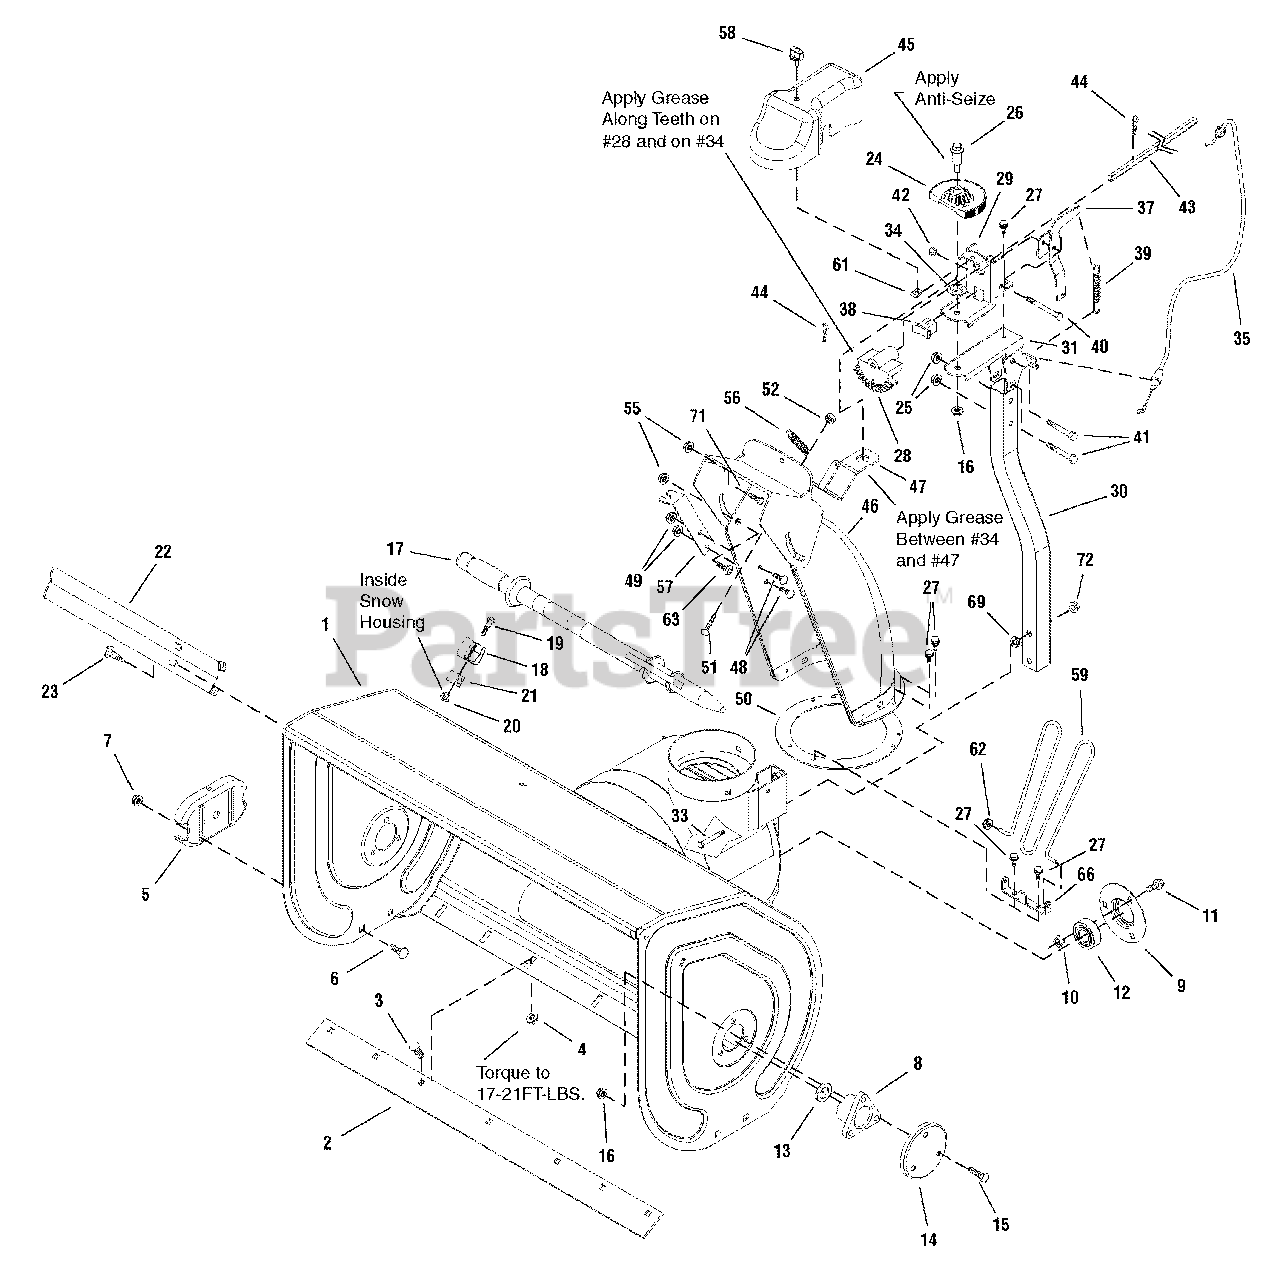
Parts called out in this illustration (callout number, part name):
1	HOUSING ASSEMBLY, 26"
1	HOUSING ASSEMBLY, 28"
1	HOUSING ASSEMBLY, 30"
1	HOUSING ASSEMBLY, 32"
2	BLADE, Scraper 26"
2	BLADE, Scraper 28"
2	BLADE, Scraper 30"
2	BLADE, Scraper 32"
3	CARRIAGE BOLT, 5/16-18 x 5/8 G5
4	NUT, Hex Flange 5/16-18 Two-Way Lock
5	SKID, Shoe Reversible
6	CARRIAGE BOLT, 3/8-16 x 3/4 G5
7	NUT, Hex Flange 3/8-16 ESNA
8	BEARING, Flange
9	BEARING, Retainer
10	RETAINER, Nut, 5/16-18
11	SCREW, Hex Whiz Lock Flange 5/16-18 x 3/4
12	BEARING, Greased
13	SPACER
14	CAP, Bearing
15	CAPSCREW, Hex Head 5/16-18 x 7/8 G5
16	NUT, Hex Flange 5/16-18, Whiz Lock
17	STICK, Cleanout w/Brush
18	CLIP, Retainer
19	CAPSCREW, Hex Washer, #10 x 1-1/4
20	NUT, Hex Lock 10-24 w/Nylon Insert
21	BLOCK, Universal Pivot
22	CUTTER, Drift w/Tabs
23	SCREW, Hex Washer Head Taptite 5/16-18 x 3/4
24	GEAR, 13 Tooth
25	NUT, Hex Keps Conical Washer, 5/16-18
26	BOLT, Shoulder 5/16-18 x 3/5
27	SCREW, Hex Washer Head Taptite 1/4-20 x 1/2
28	GEAR, Sector 34 Tooth Powdered Metal
29	SUPPORT, Driver Gear
30	TUBE
31	BRACKET, Gear Support
33	NUT, Hex Keps, 3/8-16 Conical Washer
34	WASHER, Powdered Metal
35	CABLE, Chute Brake
37	BRACKET, Brake
38	ARM & PAD ASSEMBLY, Brake
39	SPRING, Extension
40	CAPSCREW, Hex Head 1/4-20 x 2-1/2 G5
41	CAPSCREW, Hex Head 5/16-18 x 2 G5
42	NUT, Hex Centerlock 1/4-20
43	ROD, Hex Chute
44	PIN, Quick
45	COVER, Chute
46	CHUTE & DEFLECTOR ASSEMBLY
47	BRACKET, Chute Support
48	CARRIAGE BOLT, 1/4-20 x 5/8 G5
49	NUT, Hex Flange 1/4-20 Whiz Lock
50	RING, Chute Base
51	SCREW, Truss Head Torx Drive 1/4-20 x 3/4
52	NUT, Hex Lock ESNA Light 1/4-20
55	NUT, Hex Flange 5/16-18 ESNA
56	SPRING, Extension
57	BRACKET, Cable
58	KNOB & SCREW ASSEMBLY
59	GUARD, Chute
61	NUT, Retainer Speed #10-24 w/Extrusion
62	NUT, Push
63	SCREW, Truss Head Trox Drive 5/16-18 x 7/8
66	BRACKET, Chute Guard
69	LOCKWASHER, Spring 3/8
71	CAPSCREW, Hex Head 5/16-18 x 3/4 G5
